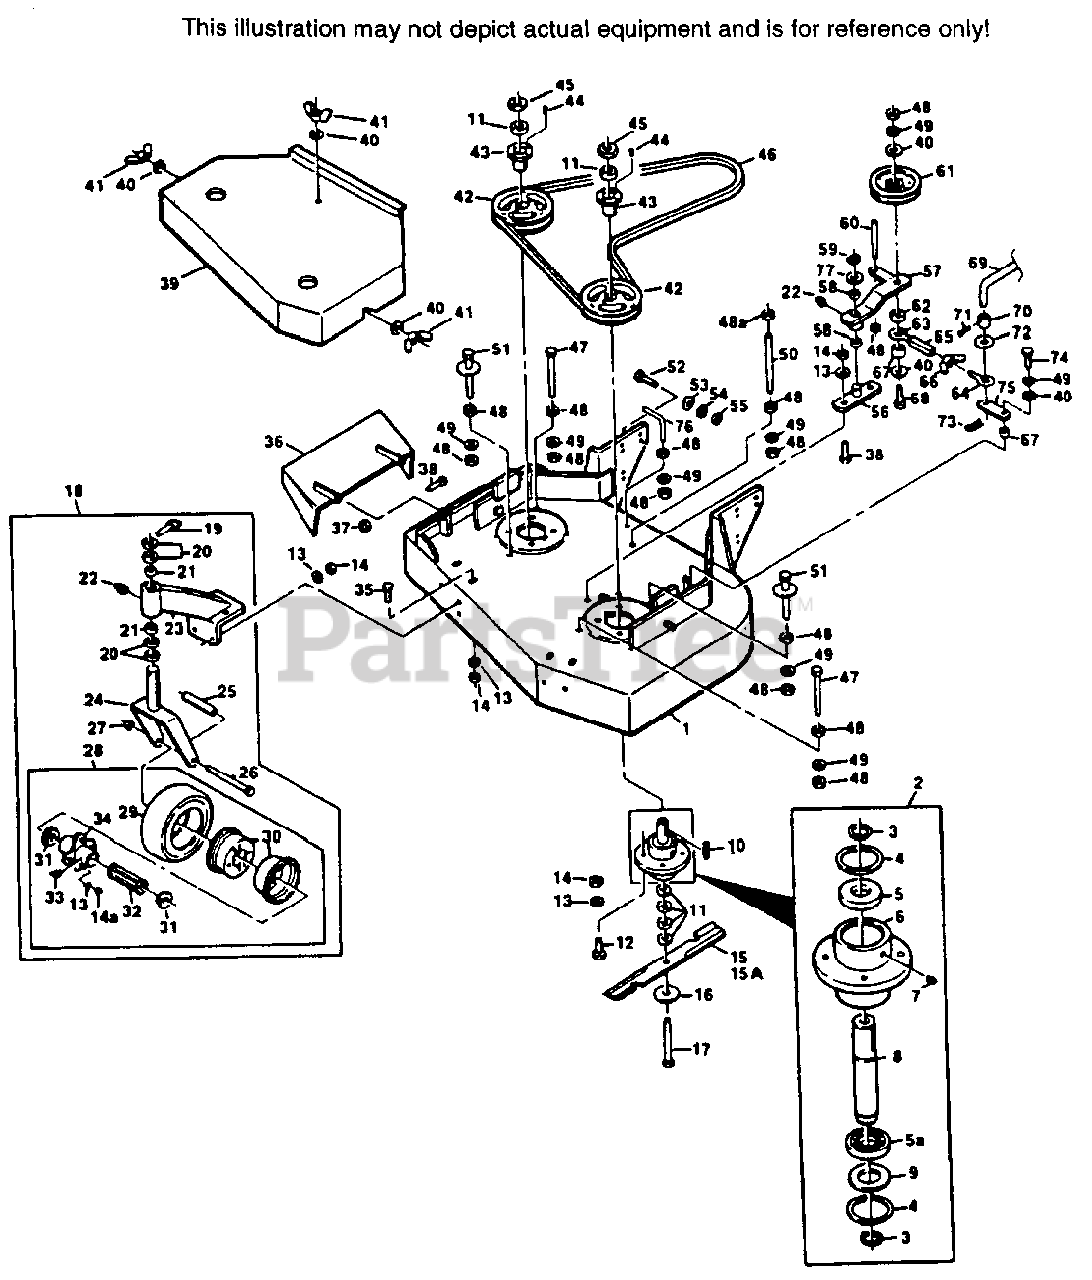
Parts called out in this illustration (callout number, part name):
1	CUTTER DECK(INCLUDES DECALS)
2	CUTTER SPINDLE ASSY.(INCLUDES ITEMS 3-9)
3	RETAINING RING, 1" EXT.-INVERTED
4	RETAINING RING, 2-7/16 INT.BSC
5	BEARING, SPINDLE
6	SPINDLE HOUSING
7	GREASE FITTING, STR., 5/16 SERR
8	SPINDLE, CUTTER BLADE
9	WASHER, 1-5/16 X 2-7/16 X 16 GA.
10	KEY, 1/4 X 1/4 X 2
11	SPACER, CUTTER BLADE
15	CUTTER BLADE 18"
15A	CUTTER BLADE 18" HI LIFT
16	FLAT WASHER, 5/8 W
17	HEX HD. BOLT, 5/8-11 X 9-1/2
18	CASTER ASSEMBLY(INCLUDES ITEMS 19-28)
19	QUICK PIN
20	SPACER, CASTER YOKE, 1/2" LONG
21	BRONZE BEARING
22	GREASE FITTING, STR. 1/4-28
23	SUPPORT ASSEMBLY
24	CASTER YOKE
25	SLEEVE, CASTER WHEEL BRG.
26	HEX HD. BOLT, 1/2-13 X 5-1/2
28	WHEEL ASSY.(INCLUDES 13-14A, 29-34)
29	TIRE ONLY CASTER WHEEL
29	INNER TUBE ONLY
30	RIM PAIR, CASTER WHEEL
31	RETAINER, BEARING, CASTER WHEEL
32	ROLLER BEARING, CASTER WHEEL
33	GREASE FITTING, 45" 1/4-28
34	HUB ASSEMBLY
36	DISCHARGE CHUTE
37	HEX NUT, 5/16-18 ELASTIC STOP
39	BELT COVER ASSEMBLY(INCLUDES DECAL)
40	WASHER, 25/64 X 15/16 X 12 GA.
41	WING NUT, 3/8-16 ELASTIC STOP
42	PULLEY(INCLUDES ITEMS 43-44)
43	TAPERED HUB
46	BELT, BLADE DRIVE
48A	HEX NUT, 3/8-16 CTR LOCKNUT
50	SUPPORT, BELT COVER
51	BELT GUIDE
53	WASHER, 15/32 X 59/64 X 16 GA.
55	HEX NUT, 7/16-14 ELASTIC STOP
56	IDLER PIVOT
57	IDLER ARM ASSY.(INCLUDES ITEMS 22 & 58)
58	BRONZE BEARING
59	RETAINING RING, 3/4 EXT,-"E"
61	IDLER PULLEY, BELT CLUTCH
62	SPACER, IDLER
63	EYEBOLT, LH
64	EYEBOLT, RH
65	TURNBUCKLE
66	WING NUT, 5/16-18
67	SLEEVE, CLUTCH ROD
69	BLADE CLUTCH ROD, LOWER
70	SLEEVE, CLUTCH ROD
72	WASHER, 33/64 X 1 X 16 GA.
73	HAIR PIN, LARGE
75	CAM LINK
76	BELT GUIDE
77	WASHER, 3/4 X 1-1/4 X .035
